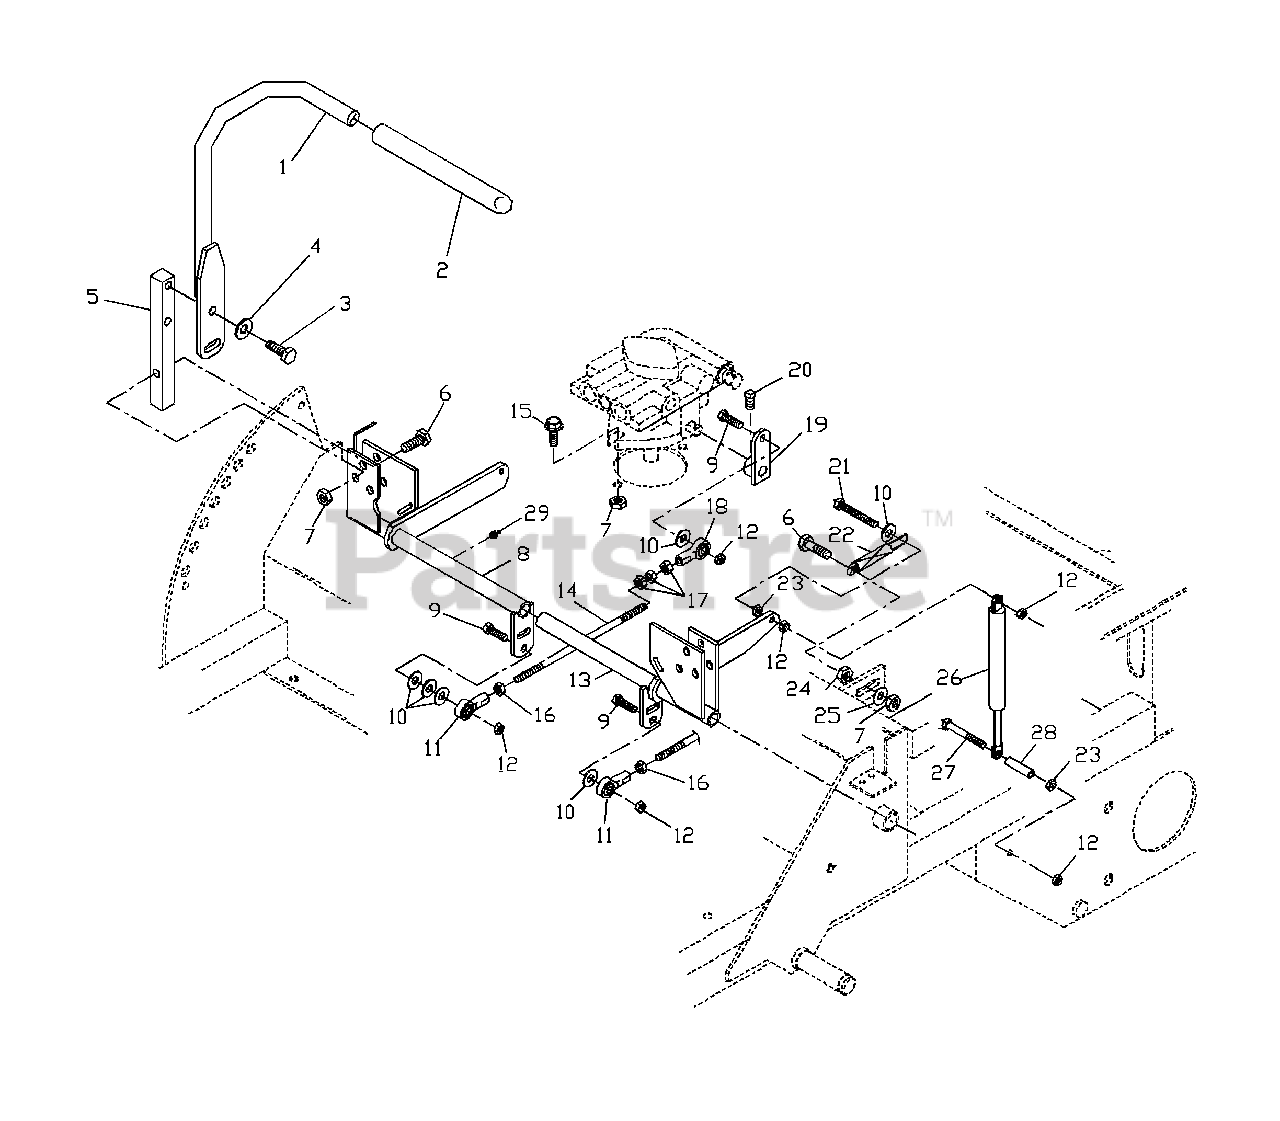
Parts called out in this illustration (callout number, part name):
1	CONTROL LEVER WLDMT
3	HCS 3/8C X 1
4	3/8 DISC SPRING WASHER
5	CONTROL ARM
6	HCS 3/8C X 1 1/2
7	NUT 3/8C CENTERLOCK
8	CONTROL WELDMENT, RIGHT
9	HCS 5/16C X 1 1/4
10	WASHER 5/16 FLAT
11	BALL JOINT, LEFT HANDED
12	NUT 5/16C CENTERLOCK
13	CONTROL WELDMENT, LEFT
14	PUMP CONTROL LINK
15	HCS 3/8C X 1 SERRATED HEAD
16	NUT 5/16F LEFTHAND
18	BALL JOINT, RIGHT HAND
19	CONTROL ARM, PUMP
20	5/16C X 5/8 SQ. HEAD
21	TAPBOLT 5/16C X 2 1/4
23	5/16C WHIZ NUT
24	3/8C WHIZ NUT
25	WASHER 3/8 FLAT
27	HCS 5/16C X 2 3/4 GRADE 8
29	ZERK
